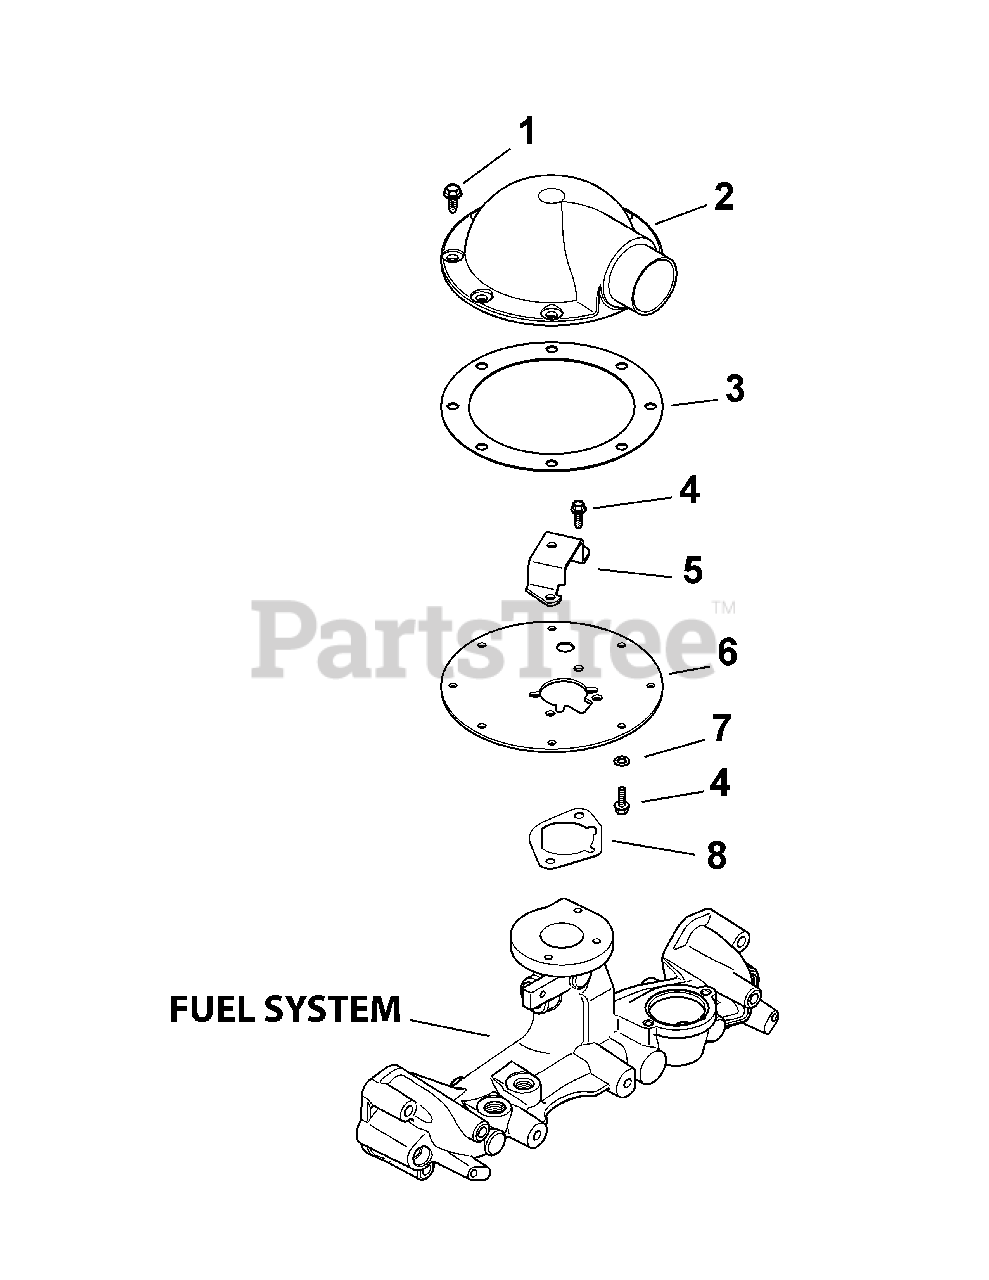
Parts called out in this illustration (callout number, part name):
1	SCREW, FLG THD FRM M6X1.0X16
2	ADAPTER, AIR INTAKE
3	GASKET, AIR CLEANER ADAPTER
4	SCREW, HVY FLG M5X.8X16
5	BRACKET, AIR CLEANER
6	ADAPTER, PLATE
8	GASKET, AIR CLEANER BASE
